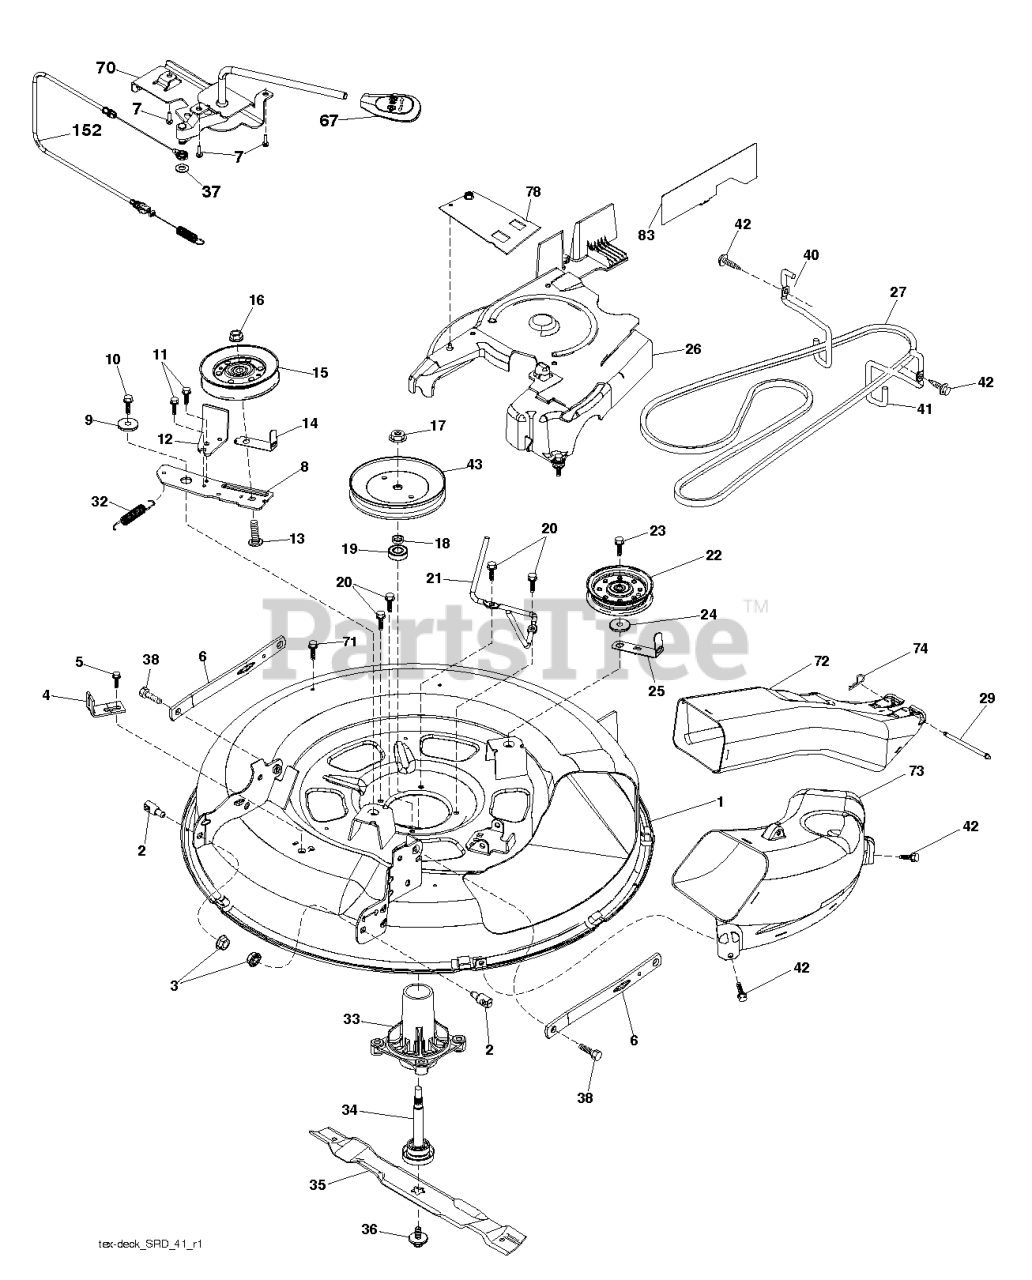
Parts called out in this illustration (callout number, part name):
1	DECK.WELDMENT.30"SRD.BLACK
2	STUD.FASTNER.W/ANTI-ROTATE
3	NUT LOCK HEX FLANGE 5/16-18
4	BRACKET.CLUTCH.CABLE
5	BOLT.5/16HEX.WHS.HD
6	ARMS.SUSP.MOWER.REAR.SRD
7	SCREW.#10 X 0.750.BOS
8	ARM.IDLER.30"SRD
9	SPACER.RETAINER
10	SCREW 3/8-16X1
11	SCREW.1/4-20X5/8
12	RP ARM.BRAKE.MOWER.38"LH.TEX
13	BOLT.3/8-16X1.50
14	KEEPER, BELT IDLER
15	PULLEY.IDLER.4.25
16	NUT LOCK FLG 3/8-16 UNC
17	NUT.FLANGE.LOCK.TOP
18	WASHER.SPACER.MANDREL
20	SCREW, WASHER HEAD
21	KEEPER.BELT.MANDREL.30"
22	PULLEY.IDLER.FLAT.UNPLATED
23	SCREW LT
24	WASHER
25	KEEPER.BELT.30"SRD
26	COVER.ASM.MANDREL.30"
27	V-BELT.DRIVE.MOWER.30"
29	PIN.HINGE.30".SRD
32	SPRING RETURN
33	RP.HOUSING.MANDREL.4PT.
34	SHAFT.ASM.MDRL.N/GREASE.38
35	BLADE.MOWER.BAGGING.30"
36	BOLT.WASHER.ASM.7/16-2
37	WASHER
38	BOLT.SHOULDER
40	KEEPER.BELT.ENGINE.LH.LT.SRD
41	KEEPER.BELT.ENGINE.RH.LT.SRD
42	SCREW, 3/8-16X3/4
43	PULLEY, MANDREL 6.5 PD
67	HANDLE.CLUTCH.CABLE.LT
70	CLUTCH.ASM.MANUAL.LT.PRED
71	SCREW 3/8-16X1/2
72	CHUTE.UPPER.SRD.30R"
73	CHUTE.LOWER.SRD.30R"
74	RETAINER-SPRNG RB
78	GUARD ARM CLUTCH
152	CLUTCH CABLE
